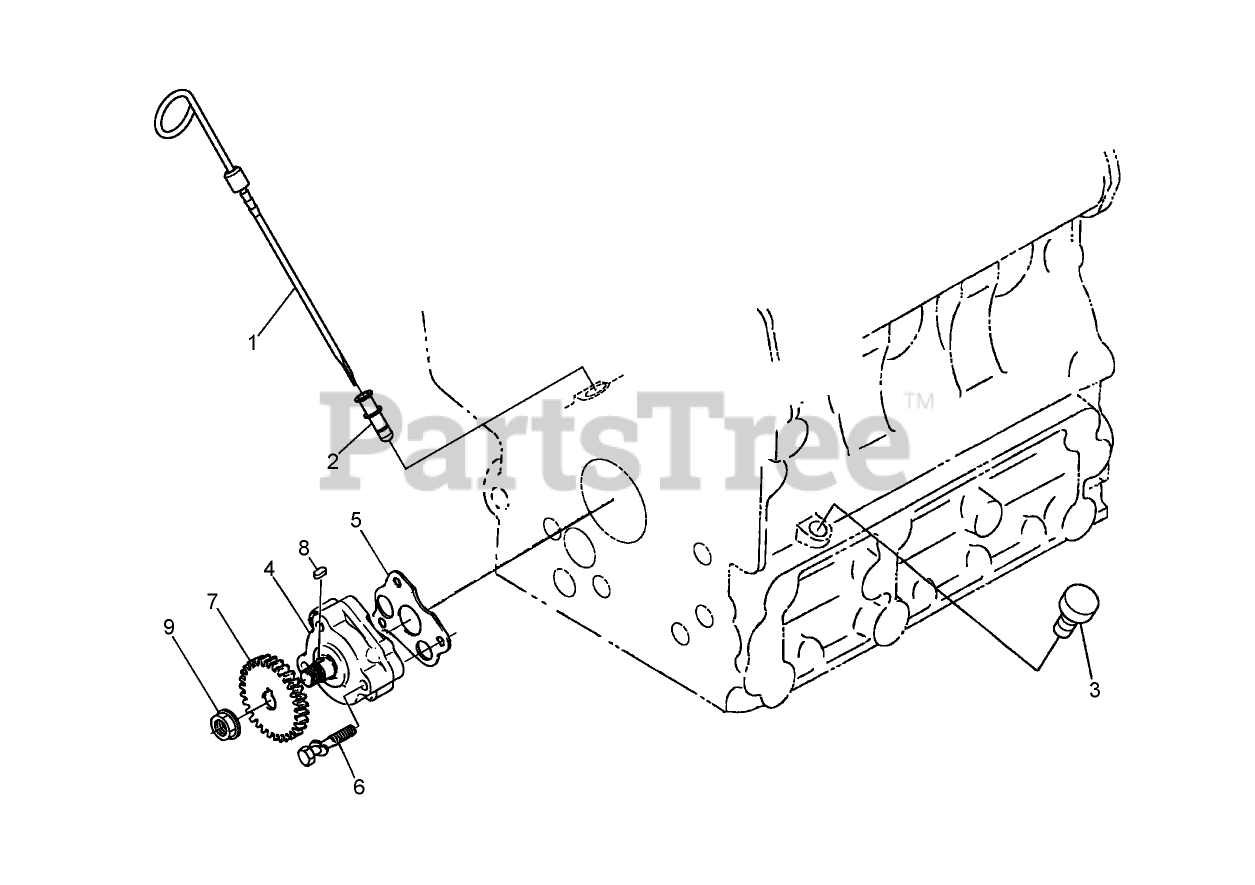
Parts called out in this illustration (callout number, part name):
1	GAUGE-OIL
2	GUIDE-GAUGE, OIL
3	PLUG-GAUGE, OIL
4	OIL PUMP ASM
5	GASKET-PUMP, OIL
7	GEAR-DRIVE, OIL PUMP
8	KEY-FEATHER
9	NUT-FLANGE
